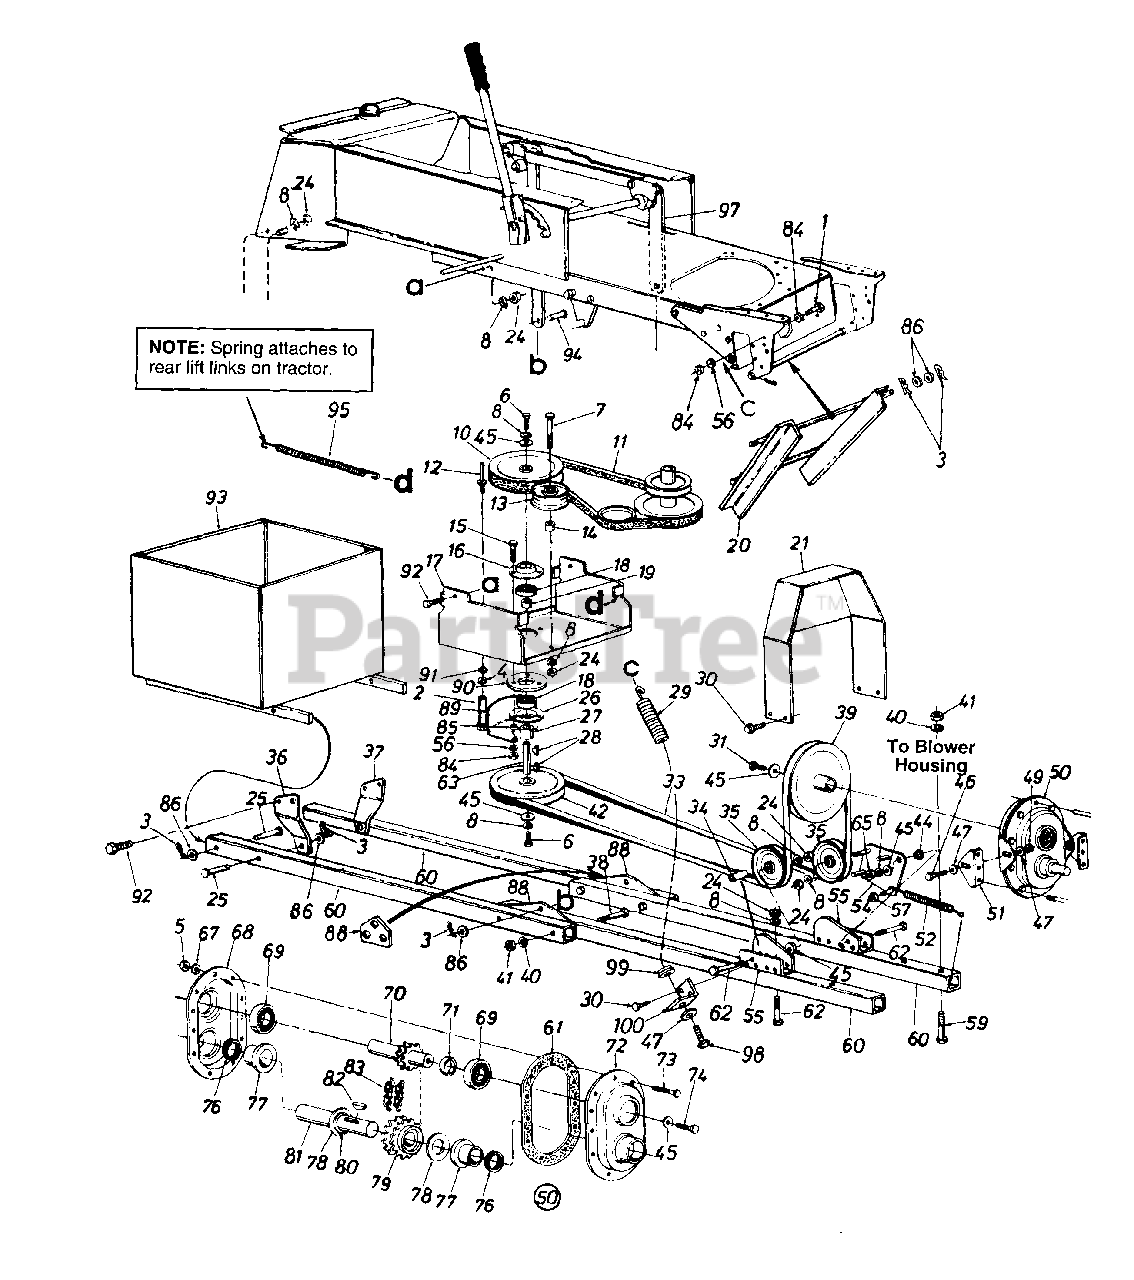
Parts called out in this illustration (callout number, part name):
1	Hex Bolt 5/16-24 x 2" Lg.
2	Clevis Pin Spec. 3/8" Dia. x 2.62" Lg.
3	Intern. Cot. Pin
4	L-Wash. 1/4" I.D.
5	Hex Nut 1/4-28 Thd.
6	Hex L-Scr. 3/8-24 x 1.0" Lg.
7	Hex Bolt 3/8-16 x 2.25" Lg.
8	L-Wash. 3/8" I.D.
10	5/8" "V"-Pulley .79" I.D. x .65" 0 D.
11	V-Belt
12	Belt Guard Pin
13	Fl-Idler 3.75" O.D.
14	Spacer .385" I.D. x .63" O.D. x .76"
15	Hex Bolt 5/16-24 x 1.50
16	Open Brg. Hsg.
16	Open Brg. Hsg. Ass'y.
17	Carr. Brkt.
18	Ball Brg. .787" 1.0.
19	Spacer .8" I.D. x 1" O.D.
20	Guide Brkt. Ass'y.
21	Belt Cover Ass'y.
24	Hex Nut 3/8-16 Thd.
25	Clevis Pin .50" Dia. x 1.75" Lg.
26	Brg. Hsg. Ass'y.
27	Spacer. 8" I.D. x 1" O.D. x .125"
28	Woodruff Key 3/16" x 5/8" HT
29	Helper Spring
30	Hex Wash. HD-Tap Scr. 5/16-18 x .50
31	Hex L-Scr. 3/8-24 x 1.0" Lg.
33	V-Belt
34	Spacer .39" I.D. x .62" O.D. x 1.74" Lg.
35	V-idler Pulley
38	Hex Bolt 1/2-13 x 4.0" Lg.
39	5/8" "V"-Pulley 7.5" O.D.
40	L-Wash. 1/2" I.D.
41	Hex Nut 1/2-13 Thd.
42	5/8" "V"-Pulley
44	Shld. Spacer
45	Fl-Wash. .4" I.D. x 1.25" O.D. x .16"
46	Hex Bolt 5/16-18 x 1.25" Lg.
47	Bell-Wash. .345" I.D. x .88" O.D. x .06"
49	Hex Nut 5/16-18 Thd.
50	Comp. Chain Gear Box Ass'y.
51	Gear Box Support Brkt.
52	Ext. Spring .6" Lg.
56	L-Wash. 5/16" I.D.
57	Hex Nut 3/8-24 Thd.
59	Hex Bolt 1/2-13 x 3" Lg.
60	Sq. Tubing 43" Lg.
61	Gasket
62	Hex Bolt 3/8-16 x 3" Lg.
63	Shaft - .787" Dia. x 3.81" Lg.
65	Hex L-Nut 3/8-16 Thd.
67	Wave Spring Wash. .27" I.D. x .51" O.D. x .03"
68	Complete Gear Hsg. Half - L.H.
69	Ball Brg. 1" I.D. x 2" O.D.
70	11-2 x .5 Pitch Sprocket Shaft Ass'y.
71	Spacer 1" I.D. x 1.18" O.D. x .44"
72	Comp. Gear Hsg. Half - R.H.
73	Hex Bolt 1/4-28 x 1" Lg.
74	Hex L-Scr. 3/8-24 x 1" Lg.
76	Oil Seal 1.25" I.D.
77	Flange Brg. 1.25" I.D.
78	Fl-Wash. 1.25" I.D. x 2" O.D. x .036"
79	DBL Sprocket 19-2 Teeth x .5" Pitch
80	Snap Ring for 1.25" Dia. Shaft
81	Gear Shaft 1.25 Dia. x 6" Lg.
82	Hi-Pro Key 1/4" x 7/8"
83	40-2 Chain 1/2" Pitch x 25 Links
83	Master Link #40 Type IV
84	Hex Nut 5/16-24 Thd.
85	Spacer .380" I.D. x .625" O.D. x .227
86	Fl-Wash. .53" I.D. x 1" O.D. x .06"
88	Attaching Plate
90	Spindle Spacer
91	Hex L-Nut 1/4-20 Thd.
92	Hex Bolt 3/16 x 1" Lg.
95	Extension Spring
97	Deck Lift Link Ass'y.
98	Hex Bolt 5/16-18 x 1.5" Lg.
99	Spring Insert
100	Spring Mtg. Brkt.
